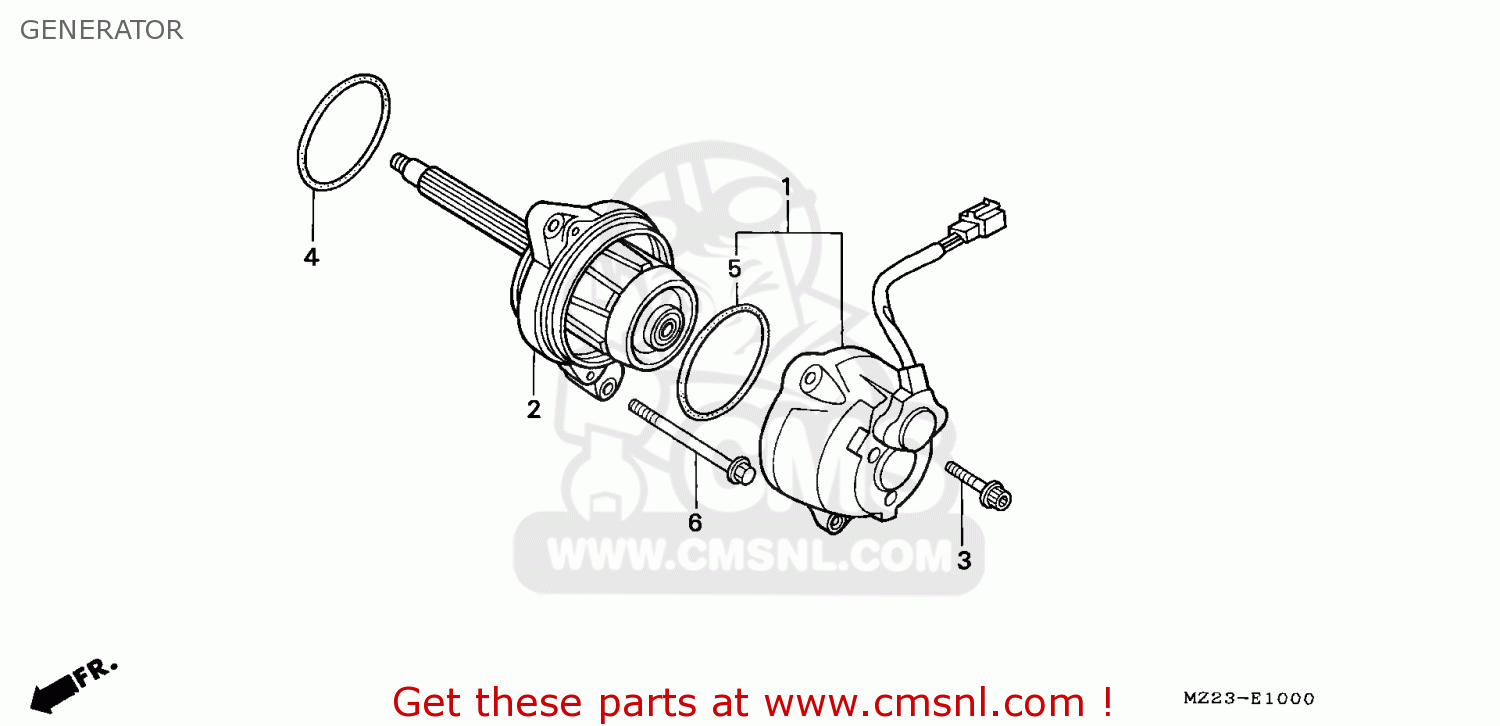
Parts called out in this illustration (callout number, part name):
1	COVER ASSY AC GEN
2	CASE AC,GEN
3	BOLT,FLG.SOC.6X28
4	O-RING,90X2.3 (AR
5	O-RING,95.5X2.4
6	BOLT,FLANGE,8X45
